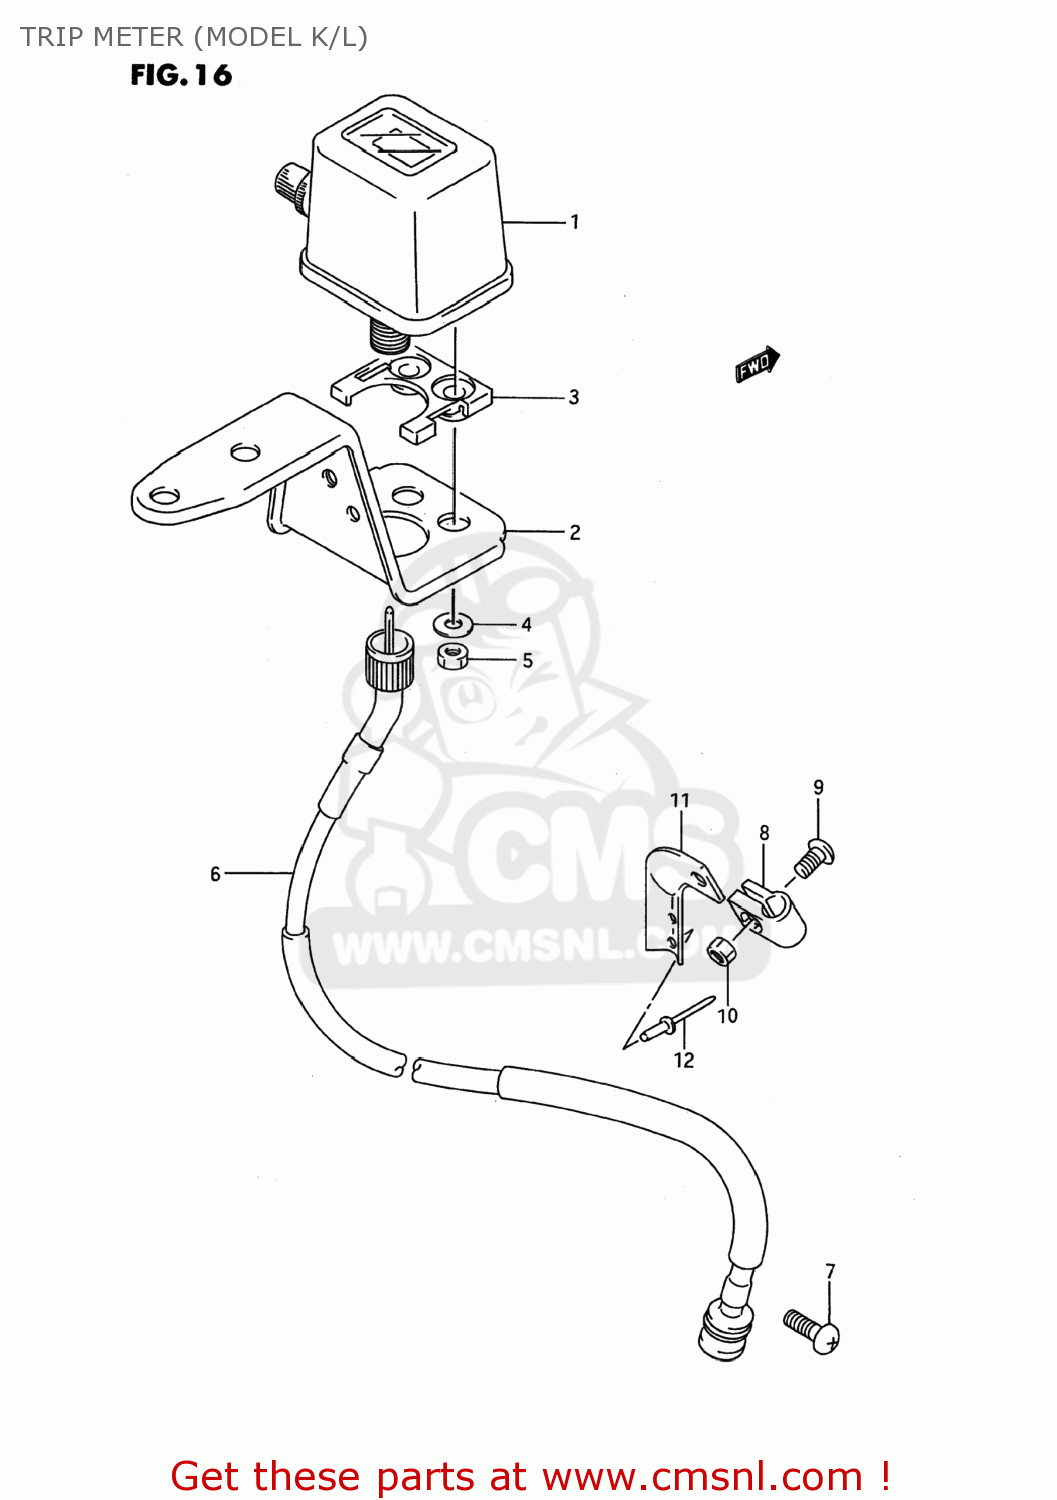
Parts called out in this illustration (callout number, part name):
1	TRIP METER
2	BRACKET
3	CUSHION,TRIPMETER
4	WASHER,METER
5	NUT
6	CABLE ASSEMBLY,TRIPMETER
7	SCREW
8	CLAMP,FR BRAKE CABLE
9	SCREW
10	NUT
11	BRACKET,METER CABLE GUIDE
12	RIVET
